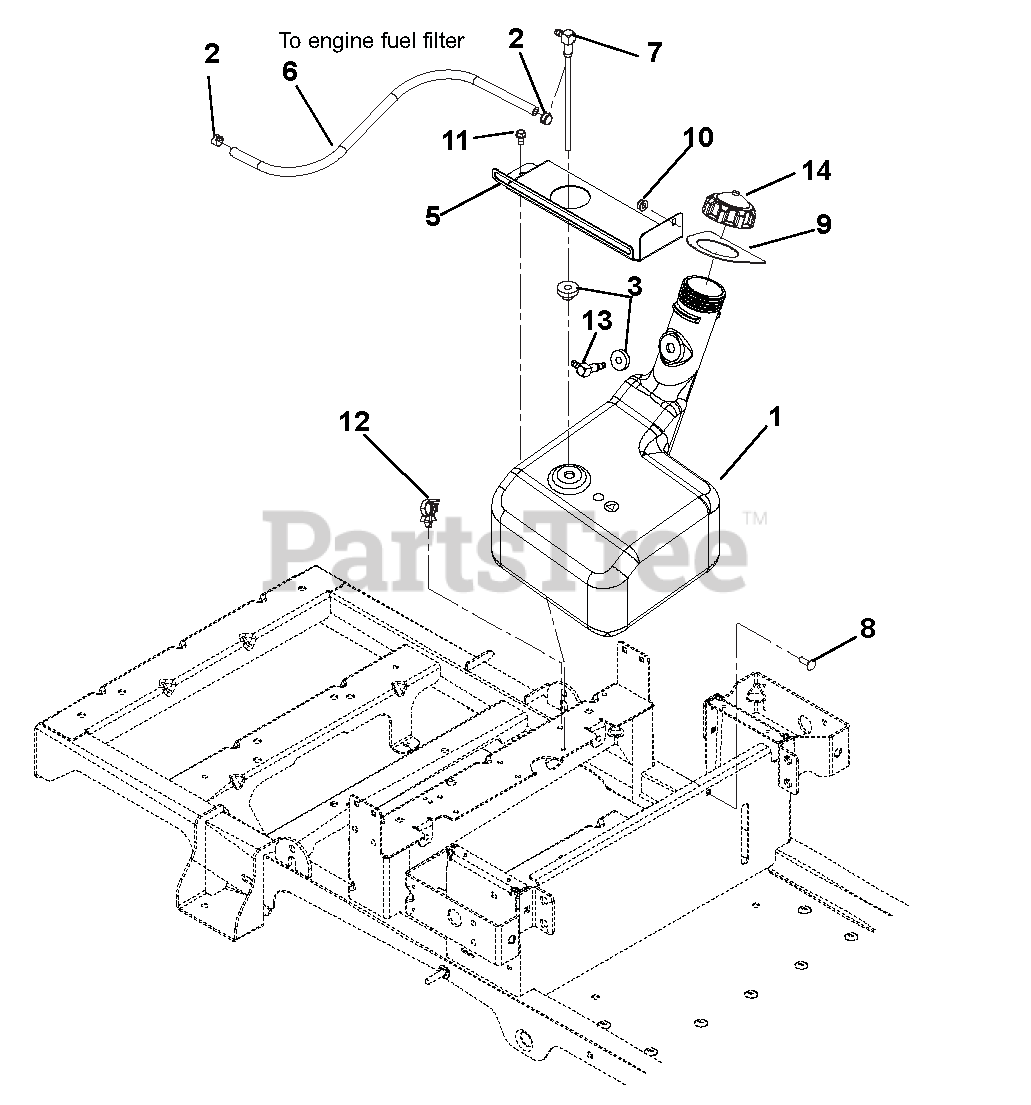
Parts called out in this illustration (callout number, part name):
1	TANK, ZOOM/WAW NON-PERM. FUEL
1	FUEL TANK
2	CLAMP, FUEL LINE
3	BSHG-FLG .375X1.062X.625 NITR
4	BSHG-FLG .375X1.062X.625 NITR
5	BRKT, TANK STRAP
6	HOSE, .25 LOW-PERM BULK GAS
7	FUEL PICK UP TUBE
8	@BLT-RDHDSQNK .25-20X.75 G5YZ
9	SEAL-TANK NECK
10	@NUT-LK-NYL-FLG .25-20 YWZC
11	SCR-TAP .25-20X.50 HWH TR YWZ
12	WIRE CLIP
13	FITTING, 90 DEG FUEL-PLASTIC
14	CAP, 2.25" ONE-WAY VENT FUEL
14	FUEL CAP
